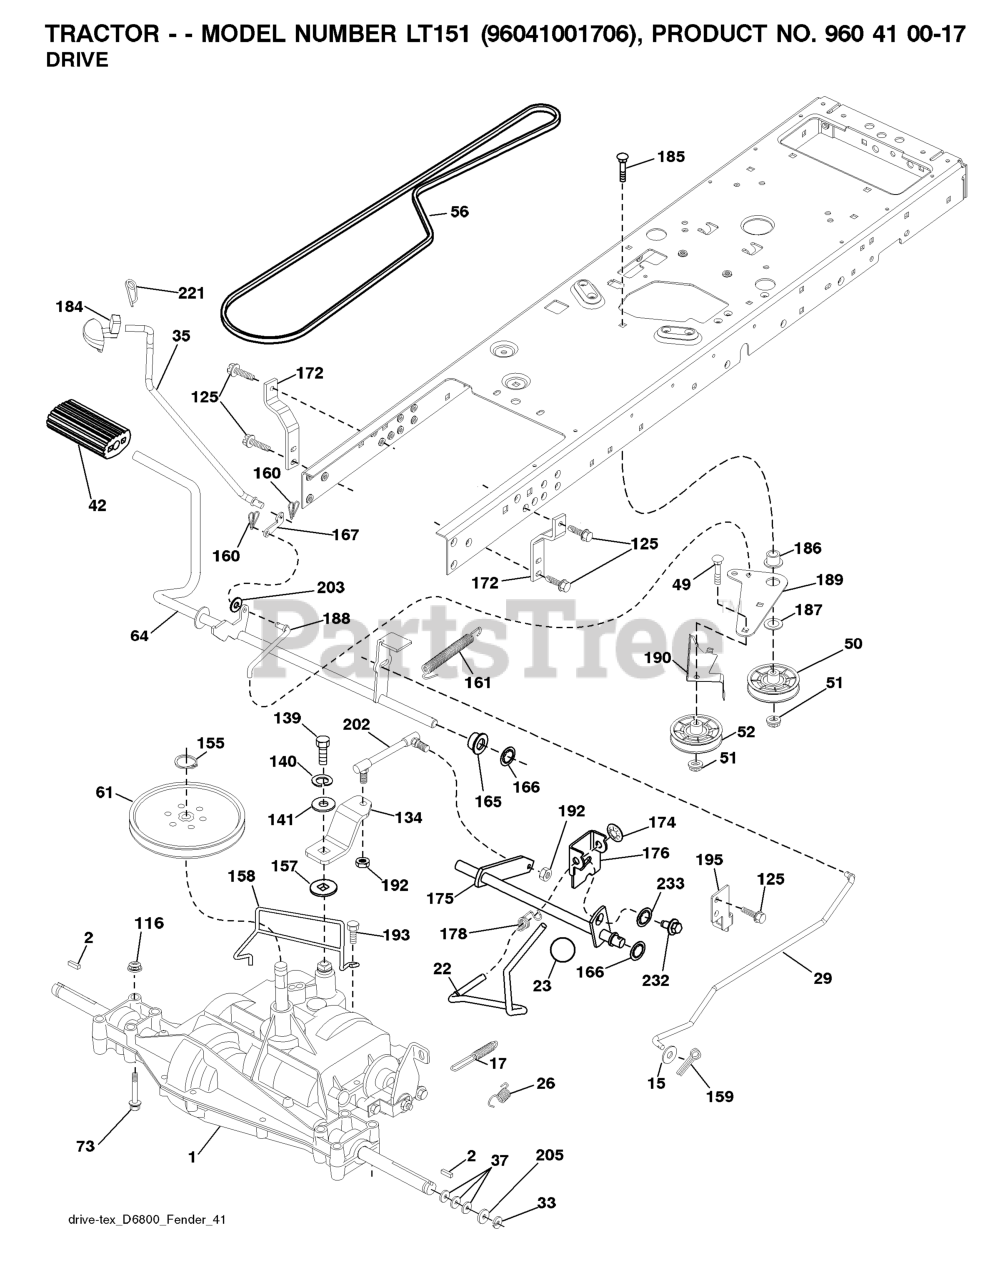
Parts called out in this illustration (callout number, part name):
2	SQUARE KEY
15	WASHER
17	SPRING.BRAKE.PEERLESS.TEX
22	ROD.SHIFT.FENDER.TLT.2006
23	KNOB.DUCKHEAD.1/2
26	SPRING.BRAKE.RTN.GR.DR
29	ROD.BRAKE.PEERLESS
35	ROD.CNTRL.PARK.PREDATOR.LT.TEX
42	PEDAL COVER T
50	IDLER.FLAT.910.OFFSET
51	NUT LOCK FLG 3/8-16 UNC
52	IDLER.V-GROOVE.910.OFFSET
56	V-BELT.TRACTOR.DRIVE.P
64	SHAFT.ASM.PEDAL.BRAKE.
73	BOLT HEX 5/16-18 GR 5
116	NUT LOCK HEX FLANGE 5/16-18
125	SCREW
134	ARM.SHIFT.
139	BOLT 1/4-28X3/4
140	LOCKWASHER
155	RETAINING RING LT
157	WASH-SHFT PLT LT
158	KEEPER.PMS.18/20.D4365
159	COTTER PIN
160	RETAINER CLIP
161	SPRING, RETURN LT
165	BUSHING.SHAFT.BRAKE.HAND
166	NUT.PUSH.625.2006
167	LATCH.BRAKE.SPRING
172	STRAP.TRQ.LH.GEAR.DRIV
174	NUT.PUSH.500.2006
175	SHAFT.ASM.SHIFT.
176	ARM.CLEVIS.ROD.SHIFT
178	SPRING.SHIFT.GT2006
184	HANDLE PARKING BRAKE
186	SPACER.RETAINER
187	WASHER 12/32X2X10GA
188	RP.LINK.CLUTCH.GROUND.DRIVE
189	BELLCRANK.GROUND.DRIVE.TEX.
190	KEEPER.BELLCRANK.DRIVE
192	NUT LOCK CENTER 1/4 -28 FNTHD
193	SCREW 5/16"
195	BRKT.ROD.BRAKE.PEERLES
202	LINK.TRANSAXLE.D6800.18/20"TEX
203	WASHER
221	RETAINER.SPRING.CLIP.H
232	BOLT FIN HEX 7/16-14 X 1
233	WASHER SERRATED
